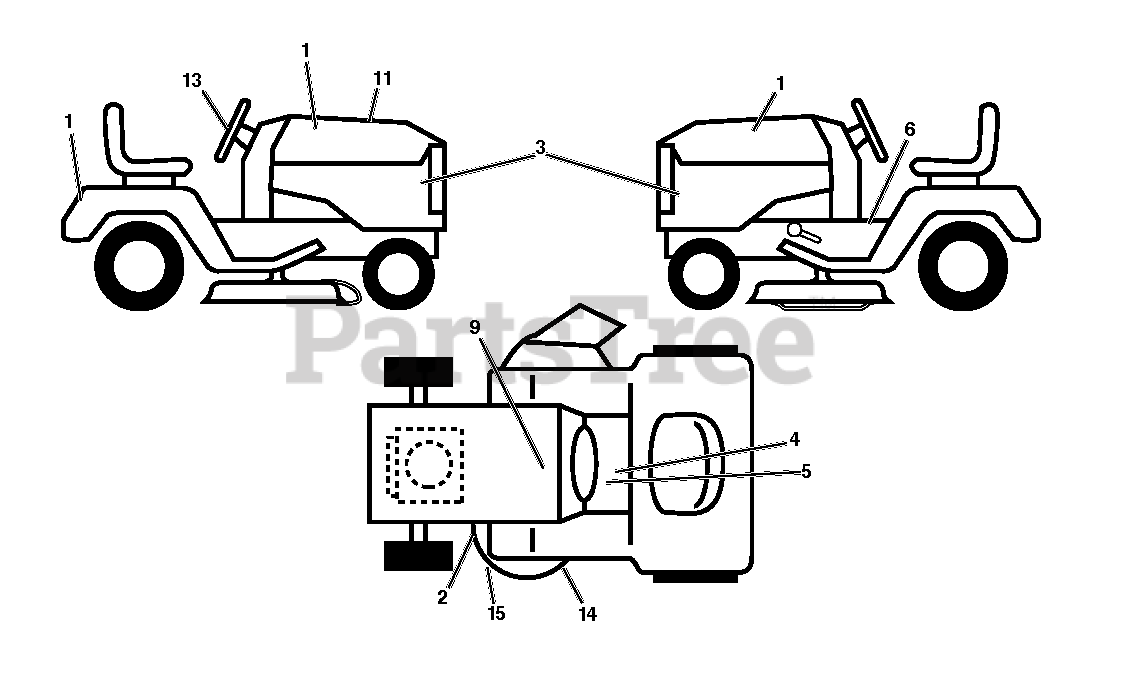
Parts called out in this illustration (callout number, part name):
2	DECAL
5	DECAL, WARNING SPARK ARRESTOR
9	DECAL BTRY SYMBOLS
11	DECAL.RPL
14	DECAL.MOWER.SCH.48/54
15	DECAL.MOWER
